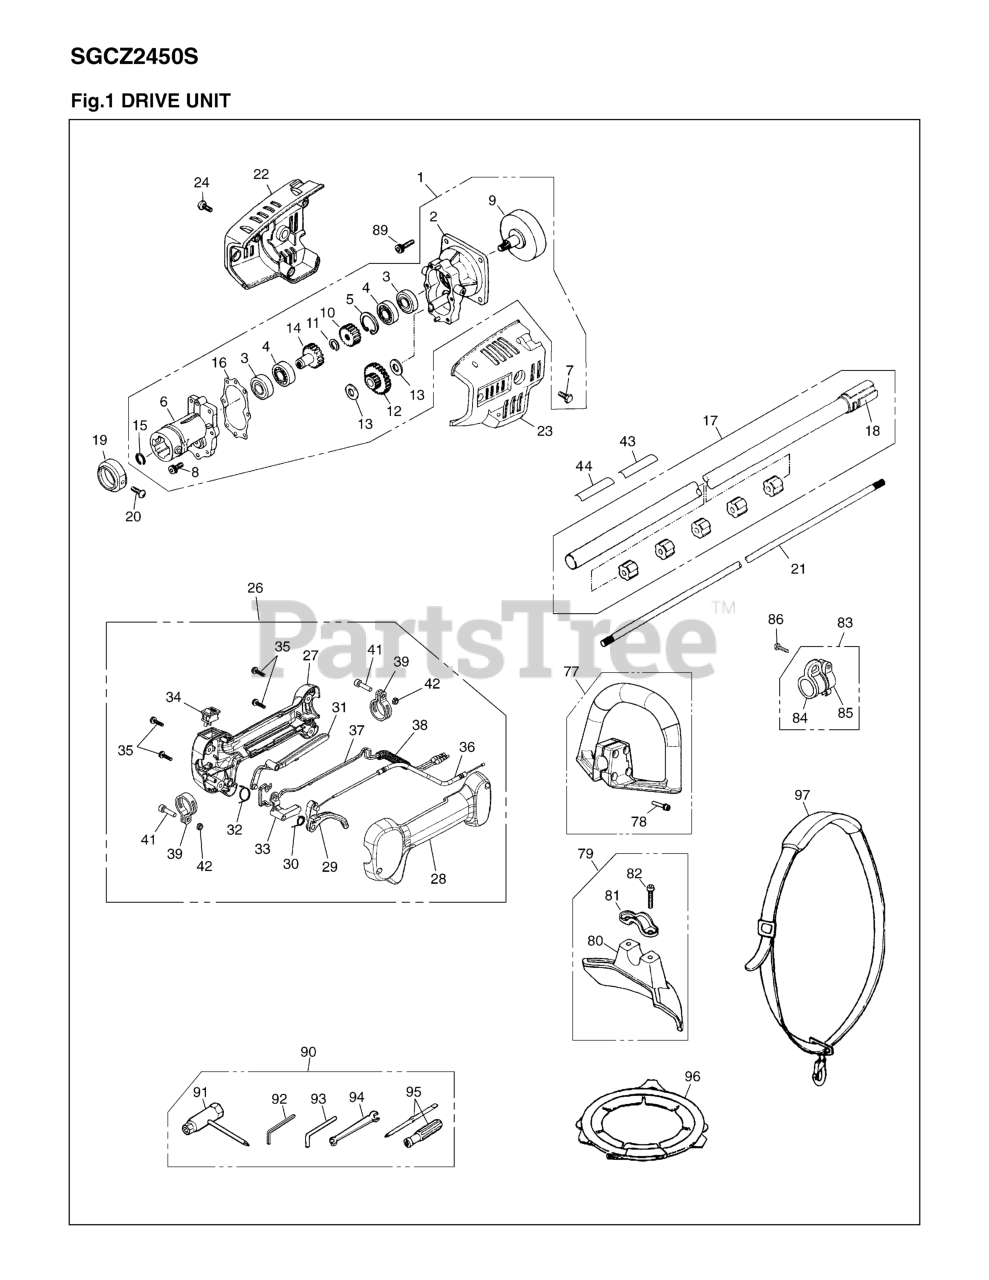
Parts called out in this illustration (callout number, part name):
1	MISSION ASSEMBLY
2	CASE, REAR COMP (RPLS -11101)
4	BEARING
5	RING, SNAP, M28 x 1.2
6	CASE, FRONT
7	BOLT, M6 x 8
8	BOLT, M5 X 20
9	DRUM
10	GEAR, PINION
11	RING, SNAP
12	GEAR (RPLS 3805-11330)
13	WASHER
14	GEAR, WHEEL
16	GASKET (RPLS 3805-11411)
17	PIPE COMP (RPLS 3805-12100)
18	CUSHION
19	CAP
20	SCREW, M5 X 10
21	SHAFT
22	COVER, RIGHT (RPLS. -11510)
23	COVER, LEFT (RPLS -11520)
29	LEVER, THROTTLE
30	SPRING, THROTTLE
31	LEVER, SAFETY
33	LEVER, JOINT
34	SWITCH
35	SCREW
36	CABLE COMP
37	CORD COMP
41	BOLT TORX
43	PLATE NAME
44	LABEL, CAUTION
77	HANDLE ASSY
78	SCREW
79	GUARD ASSY (RPLS -24000)
80	GUARD (RPLS -24110)
81	CLAMP
82	BOLT, M6 x 1.30
83	HANGER ASSY
86	SCREW
89	BOLT, M6 x 20
91	SOCKET
93	WRENCH (TOOL)
94	SPANNER
95	DRIVER
96	COVER BLADE
97	STRAP ASSY
